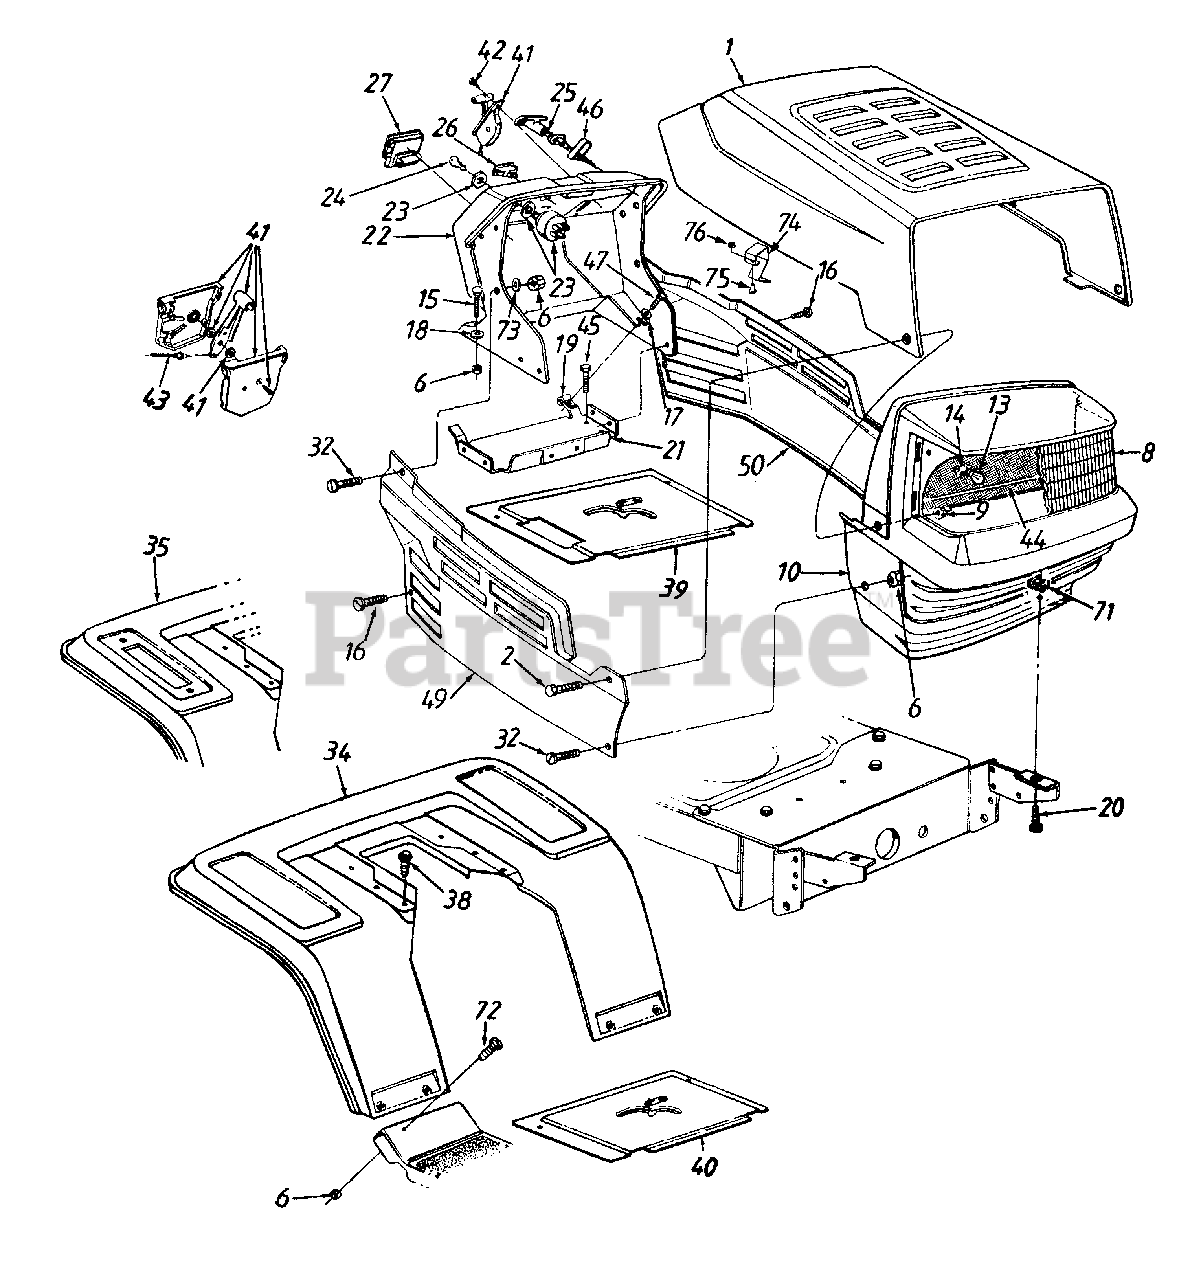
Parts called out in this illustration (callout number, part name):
6	Hex Sems Nut 1/4-20 Thd.
8	Headlight Lens w/o Logo
9	Flange L-Nut 1/4-20 Thd.
10	Grille
13	Lamp
14	Socket
15	Carriage Bolt 1/4-20 x .75" Lg.
16	Hex Wash. Hd. TT-Tap Scr. 1/4-20 x .5" Lg.
17	Fl-Wash. .281" I.D. x .73" O.D.
18	Bolt Retainer 1/4" I.D.
19	Speed Nut 1/4-20 Thd.
20	Hex Bolt 5/16-18 x .75" Lg.
23	Ignition Switch
24	Ignition Key
25	Choke Control 23" Lg.
26	Light Switch
27	Ammeter
32	Pan Hd. Scr. 1/4-20 x .75" Lg.
41	Throttle Box Ass'y.
42	Truss Mach. AB-Tap Scr.#10 x .5" Lg.
43	Throttle Control Wire 18.5" Lg.
44	Grille Reflector Label
45	Hex Wash. Hd. B-Tap Scr.5/16-18 x .5" Lg.
46	Choke Retainer
47	Hex TT-Tap Scr. 1/4-20 x .75"Lg.
72	Truss Mach. Scr. 1/4-20 x .5" Lg.
73	Fl-Wash. .283" I.D. x .75" O.D.
74	Hood Latch
75	Truss Mach. Scr. 10-24 x .5" Lg.
76	Hex Sems Nut 10-24 Thd.
17870A-0483	FENDER-RR W/FRAME - CHARCOAL GRAY (0483)
17870A-0498	FENDER-RR W/FRAME - OLD CUB YELLOW (0498)
17870A-0638	FENDER-RR W/FRAME - MTD/TROY-BILT RED (0638)
17870A-0667	FENDER-RR W/FRAME - MIDNIGHT BLUE (0667)
